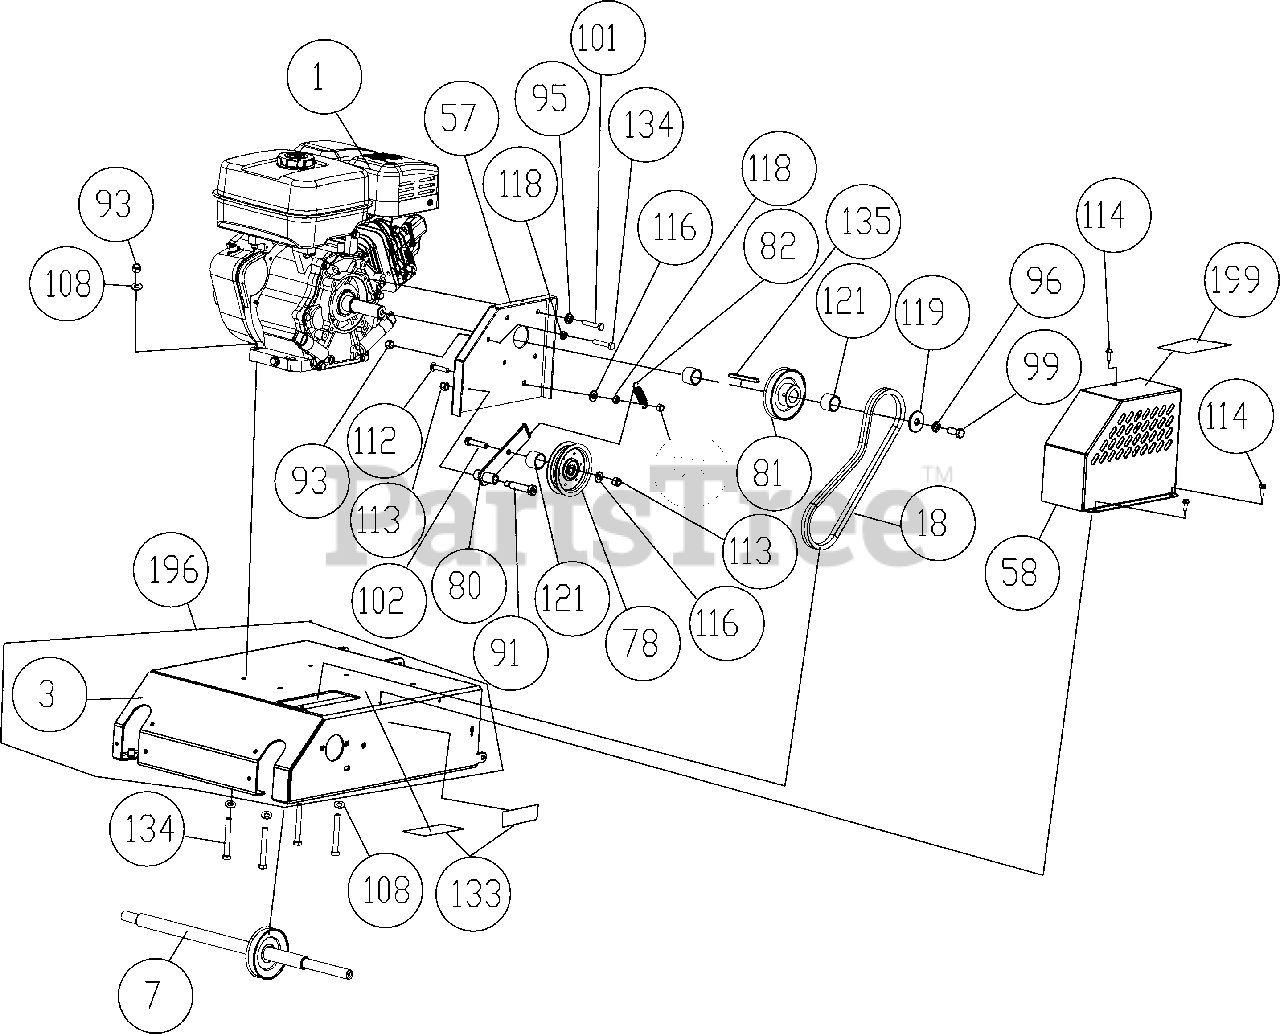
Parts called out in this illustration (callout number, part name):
1	ENGINE SUBARU 9HP
3	ENGINE BASE WA
7	JACKSHAFT WA
18	BELT - #8954-0298
57	BRACKET GUARD BELT UPPER
58	GUARD BELT UPPER OS900SP
78	PULLEY IDLER 4" OD X 3/8 BORE
80	ARM IDLER WA UPPER
81	PULLEY 3.50" OD X 1.00" BORE
82	SPRING IDLER UPPER
91	BOLT SHOULDER 1/2" X 2"
93	NUT LOCK 5/16"-18
95	WASHER SPLIT LOCK
96	WASHER LOCK 7/16' S/T MED
99	SCREWCAP 7/16"-20 X 1" HCS GR. 8 W/PATCH
101	SCREWCAP 5/16"-24 X 1" GR 8 W/PATCH
102	SCREWCAP 3/8"-16 X 1 3/4" HCS ZP
108	WASHER 5/16 FLAT
112	BOLT CARRIAGE 5/16"-18 X 1 1/2" ZP
113	LOCK NUT 3/8-16
114	SCREW SELF TAP 1/4"-20 X 5/8" HWH TYPE F
116	WASHER 3/8" SAE
118	NUT FLANGE 5/16-18 ZP
119	PLATE IMPELLER WASHER PB110
121	SPACER 1.25 OD X 1.010 ID X .938 THK
133	LABEL DANGER
134	SCREWCAP 5/16"-18 X 1 3/4" HCS ZP
135	KEY SQ 1/4" X 1"
196	ENGINE BASE WA OS900SP W/LABELS
199	LABEL MADE IN U.S.A.
